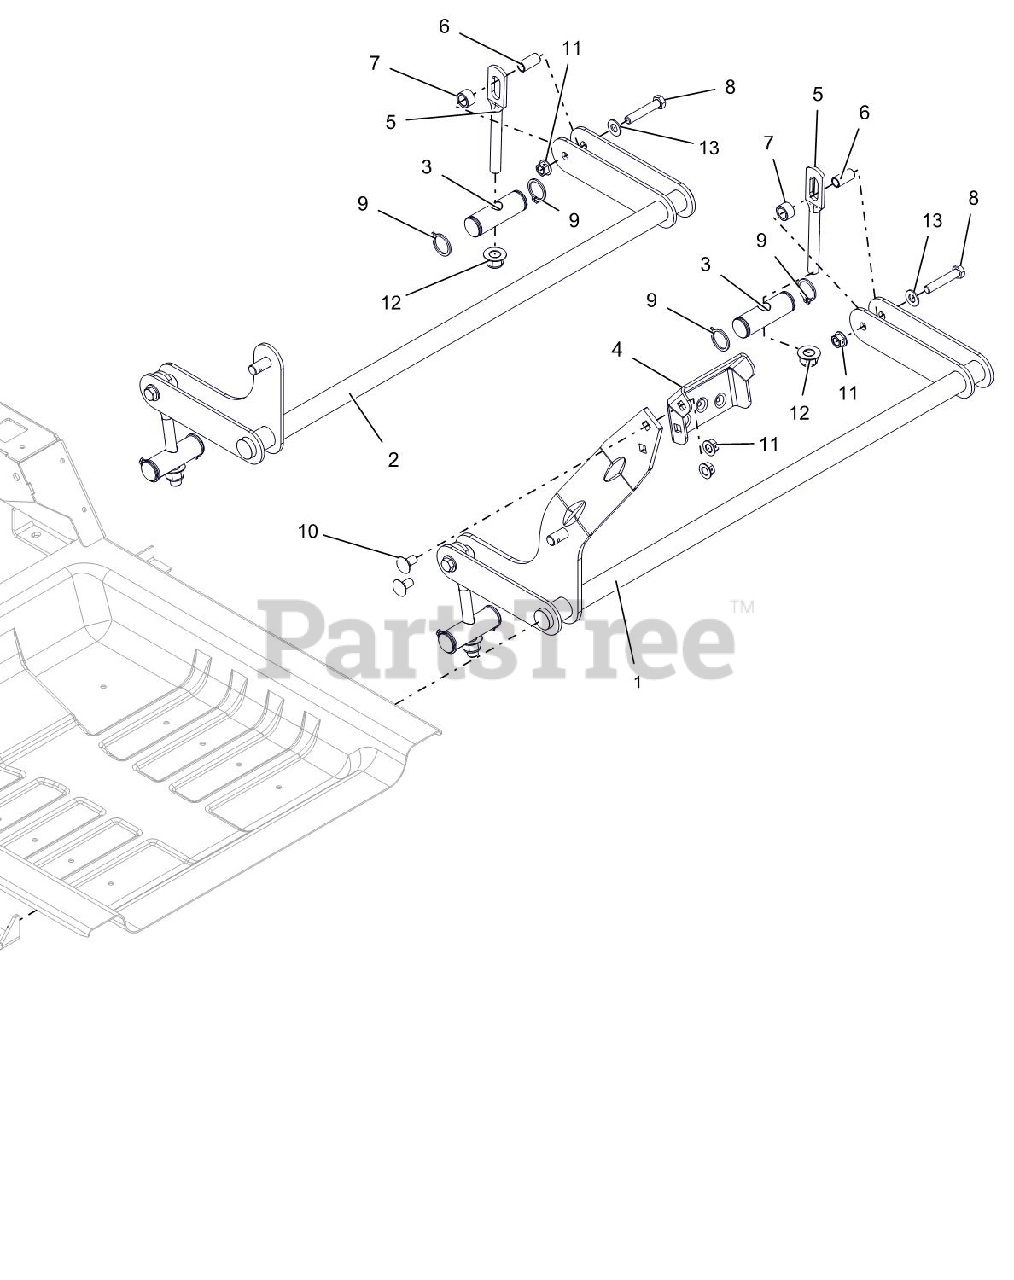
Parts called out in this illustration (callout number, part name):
1	WLDMT, FRONT DECK LIFT PIVOT
2	WLDMT, REAR DECK PIVOT
3	SHAFT, DECK LINK PIVOT
4	PEDAL, DECK LIFT (BOLT ON)
5	LINK, DECK
6	BSHG-SLV .385X.500X1.045
7	BSHG-SLV .510X.751X.475
8	BLT-HEX .38-16X2.00 GR8 YWZC
9	RG-RTNG-EXT 1.00X.078
10	BLT,RHSN .38-16X.75 G5 BFP
11	NUT-LK-CTR-FLG .38-16 YWZC
12	@NUT-LK-NYL-FLG .50-13 YWZC
13	@WSHR-FL-STL.406X.812X.065 YWZ
